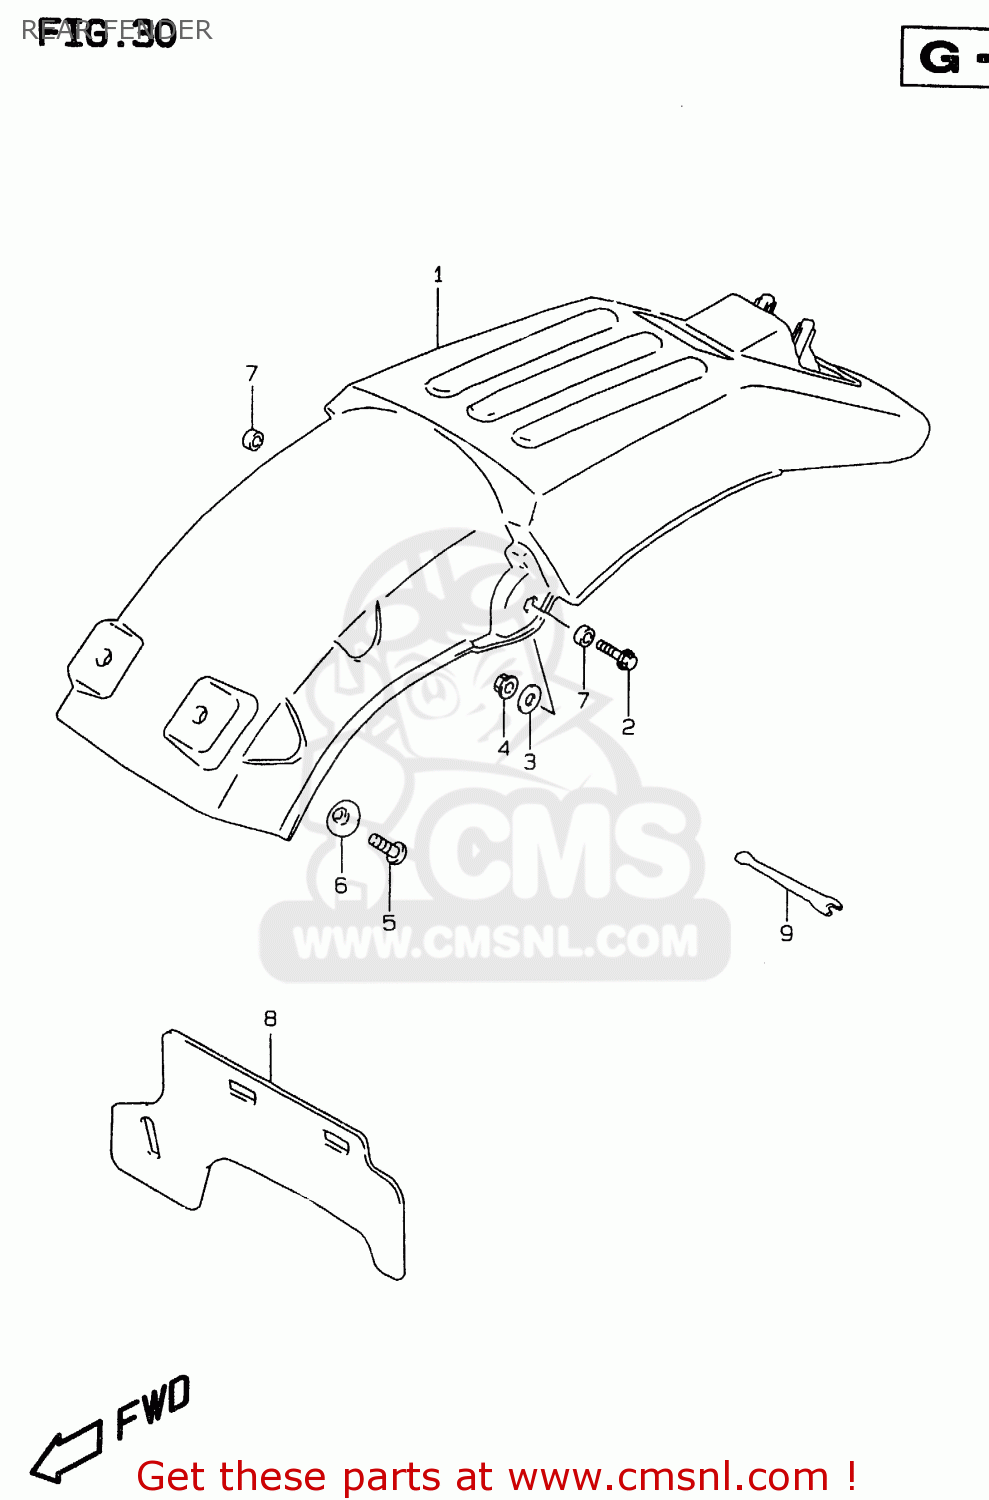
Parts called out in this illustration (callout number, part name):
1	BODY,RR FENDER
2	BOLT
3	WASHER(8.5X20X1.6)
4	NUT
5	SCREW
6	WASHER
7	SPACER(8.5X12X4)
8	MUDGUARD,RR FENDER
9	SPANNER,OPEN
